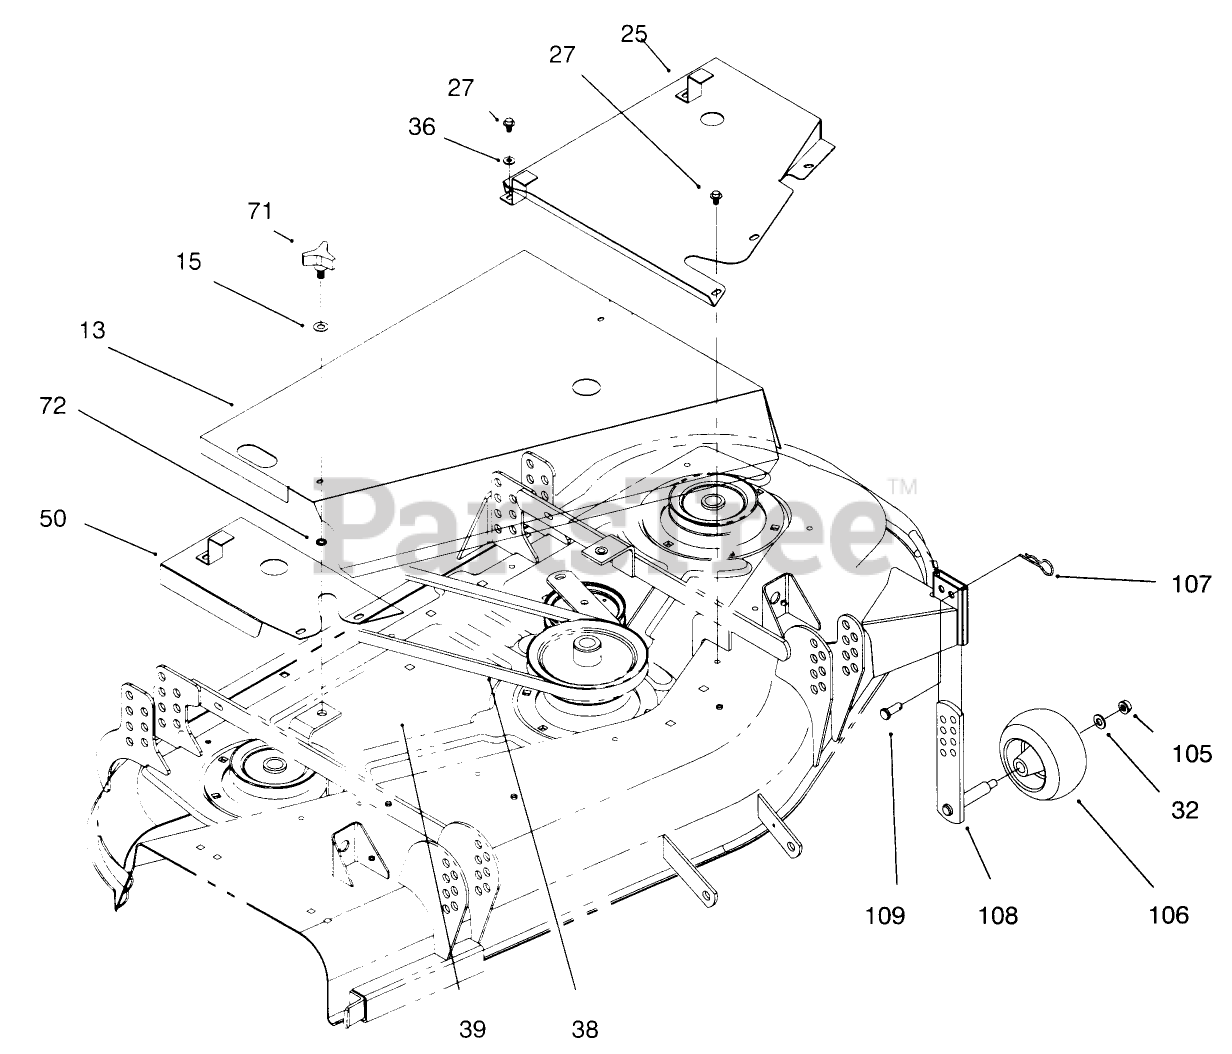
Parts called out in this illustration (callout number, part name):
13	Cover
15	WASHER-FLAT
25	Cover
27	SCREW-HHFTF
32	WASHER-FLAT
36	WASHER-FLAT
38	V-BELT
39	V-BELT
50	Cover
72	RING-RETAINING
105	NUT-LOCK, NI
106	WHEEL-GAGE
107	PIN-HAIR
108	GAGE-WHEEL
109	PIN-CLEVIS
